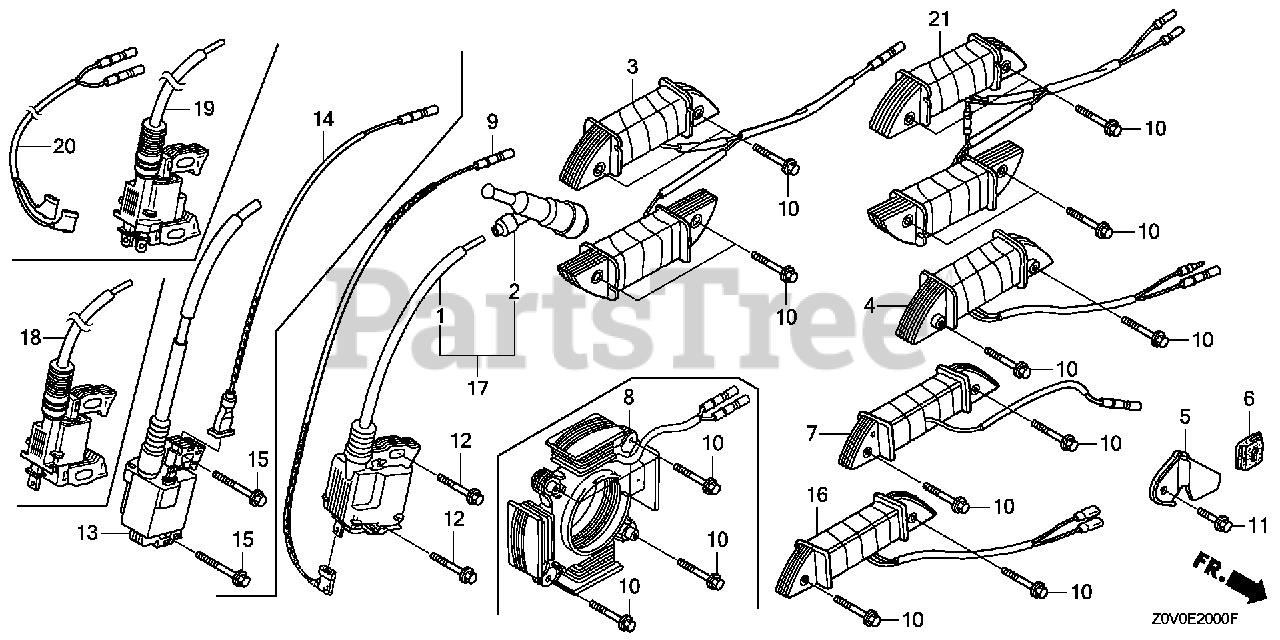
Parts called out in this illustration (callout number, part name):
1	COIL ASSY., IGNITION (TEC)
2	CAP ASSY., NOISE SUPPRESSOR (NGK)
2	CAP ASSY., NOISE SUPPRESSOR (TEC)
9	WIRE, STOP SWITCH (370MM)
12	BOLT, FLANGE (6X25) (CT200)
